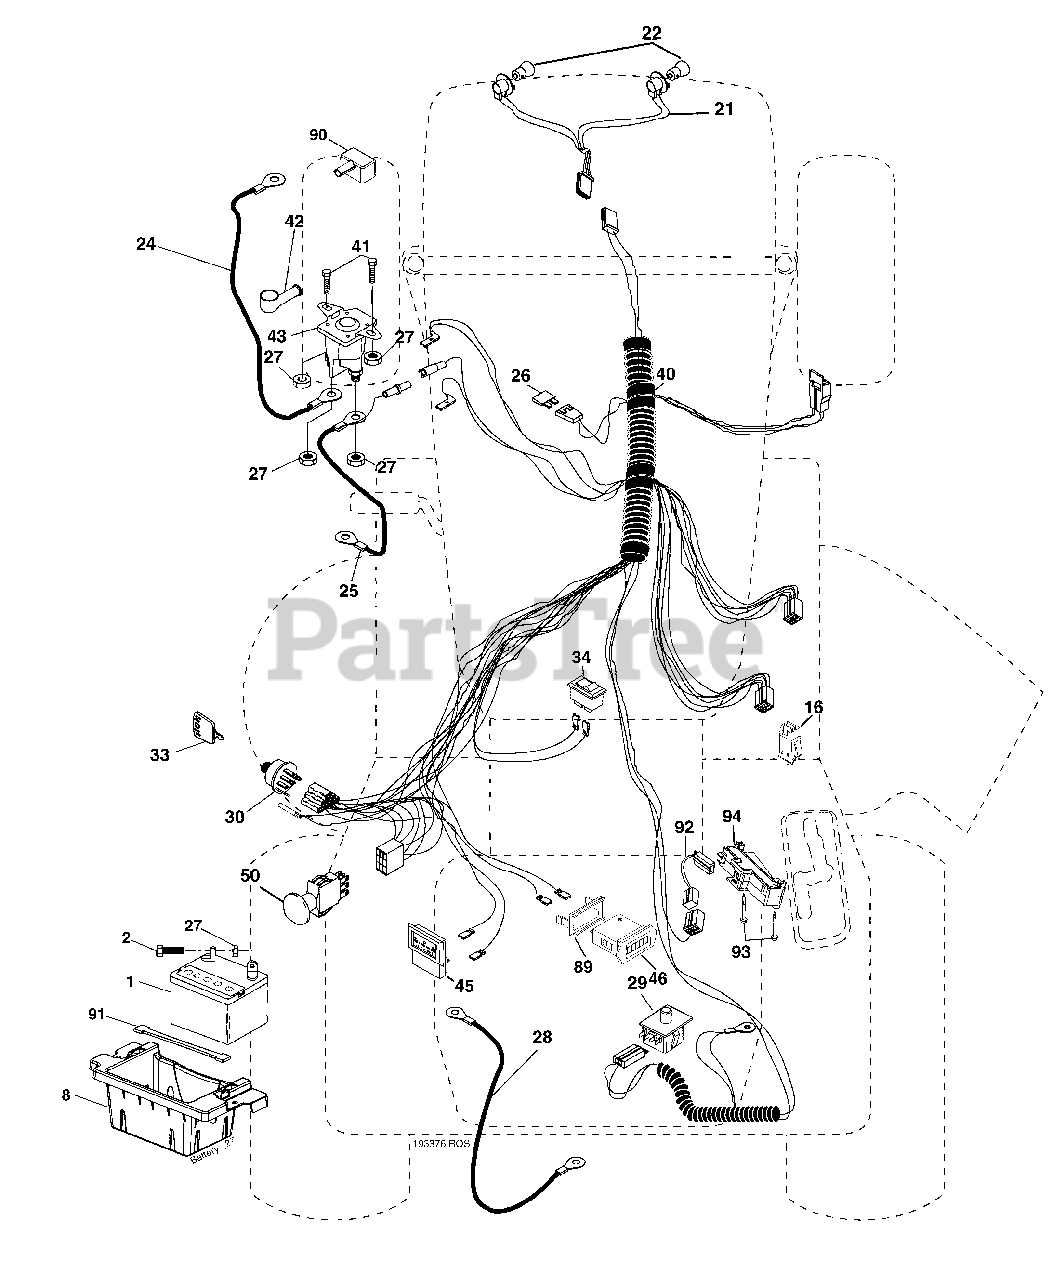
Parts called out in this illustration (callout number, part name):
1	Battery
2	Bolt Hex Hd 1/4-20 unc x 3/4
8	Box Battery
16	Switch Interlock Push-In
21	Harness Asm Light W/4152j
22	Bulb Light #1156
24	Cable Battery 6 Ga. 11" red
25	Cable Battery 6 Ga. 22" red w/16 wire
26	Fuse 20 AMP
27	Nut Keps Hex 1/4-20 unc
28	Cable Ground black
29	Switch Seat DP w/ROS
30	Switch Ign
33	Key Ign Molded Generic
34	Switch Light/Reset
40	Harness Ign.
41	Bolt 1/4-20 x 1/2
42	Cover Terminal Red
43	Solenoid
46	Hourmeter Snap-In
50	Switch PTO
89	Bracket Snap-In Hourmeter
90	Cover Terminal
91	Strap Battery
92	Harness Pigtail Reverse Switch
93	Screw Plastic 10-14 x 2.0
94	Module Reverse ROS
